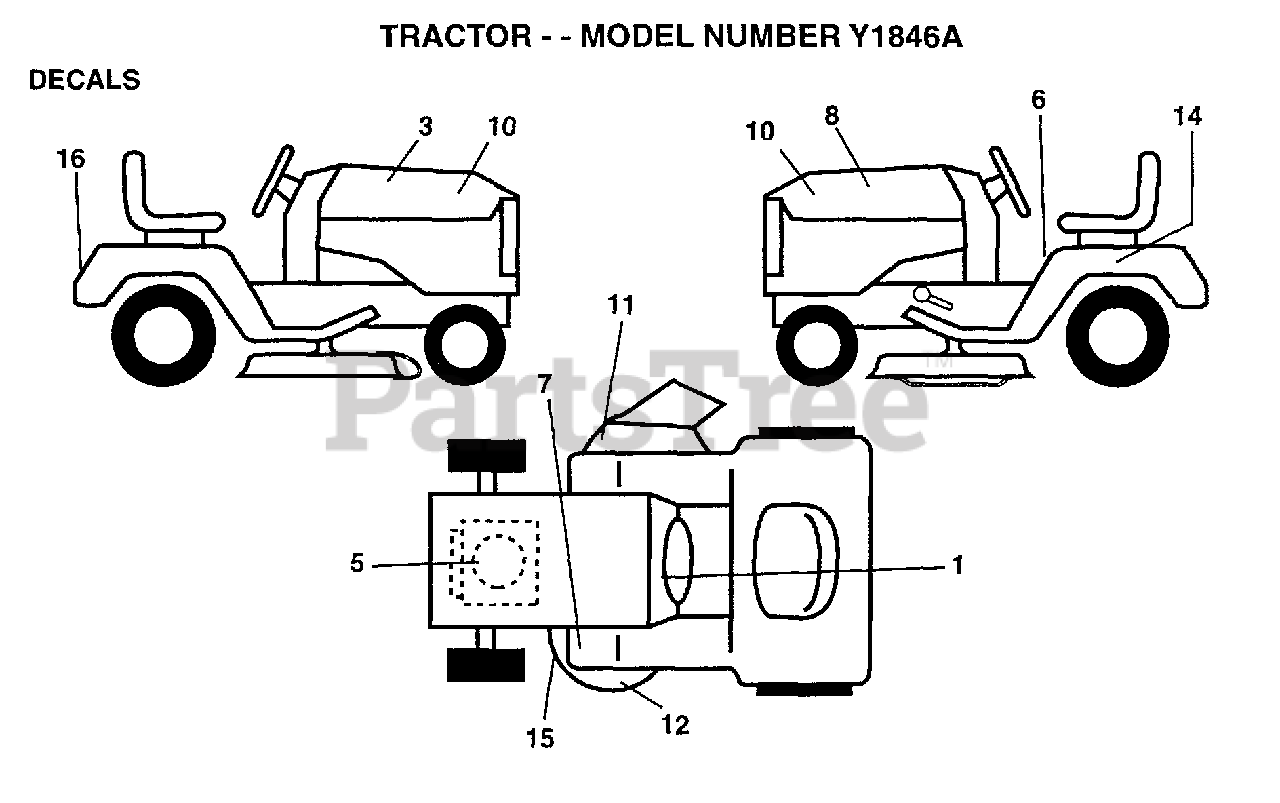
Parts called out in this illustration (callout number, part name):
1	"CLIP,INSULATOR"
2	BRKT CLUTCH
3	BOLT HXHD FIN
5	LEVER.ASM.CLUTCH
6	"BOLT, SHOULDER LT"
7	MWR CLUTCH ARM AS
8	BOLT
9	"BELLCRANK,LIFT"
10	COTTER PIN
11	WASHER
13	HANDLE.ASM.LIFT
14	SPRING COMPRESSIO
15	WASHER T
16	SPRING.RETAINER
17	"LINK,LIFT FRT"
18	TRUNION ADJ
20	BOLT
23	PIN COTTER 1/8
25	TUBE SPACER
26	ROD LIFT MOWER
27	KNOB T(3/8 HOLE)
29	CLUTCH LINK
30	NUT
31	WASHER
